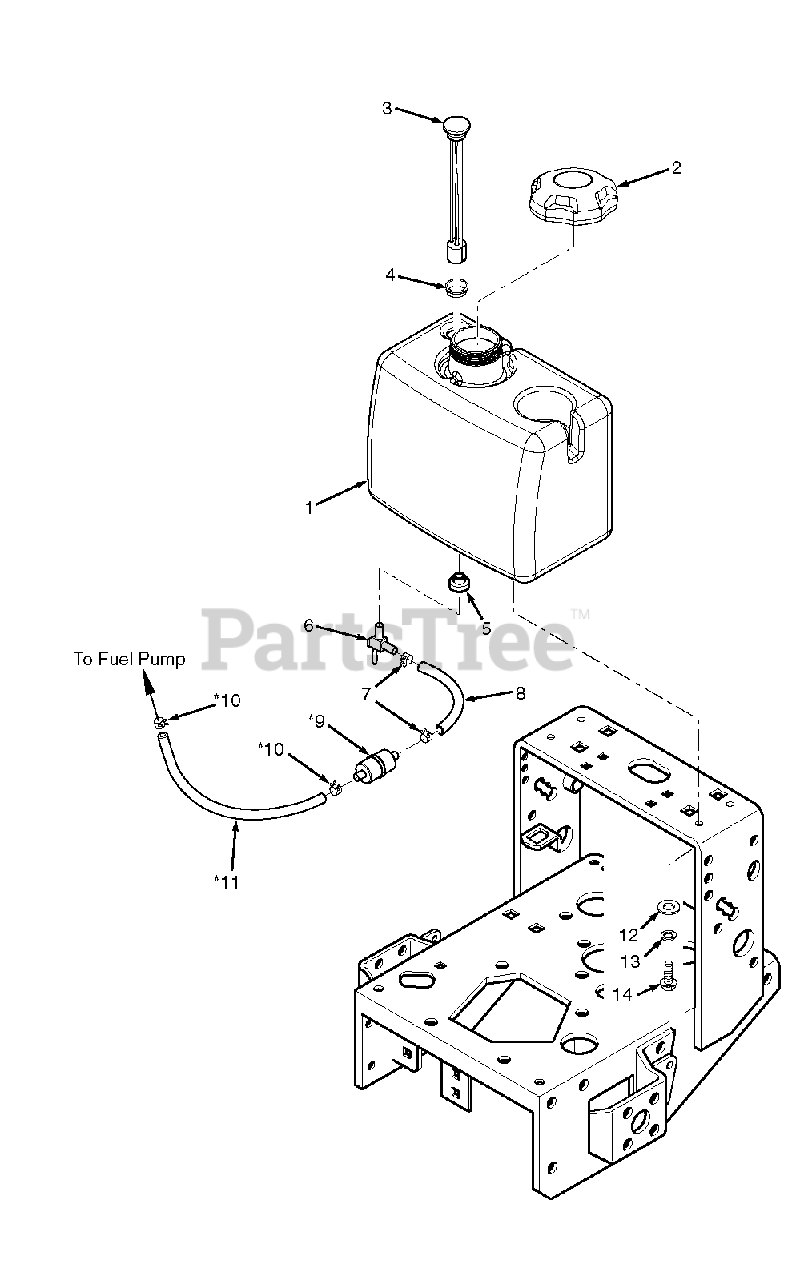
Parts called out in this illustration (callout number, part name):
1	Fuel Tank Assembly
2	Fuel Cap
3	Fuel Gauge Assembly
4	Seal, Fuel Gauge
5	Bushing, .56 Dia. Viton
6	Ball Valve w/Screen
7	Clamp, Fuel Hose
8	Fuel Hose, 1/4" ID
9	Fuel Filter
10	Clamp, Fuel Hose
11	Fuel Hose
12	Flatwasher, 5/16-.375 x .875 x .083
13	Lockwasher, 5/16" Spring
14	Bolt, Hex Head 5/16-18 x 1"
